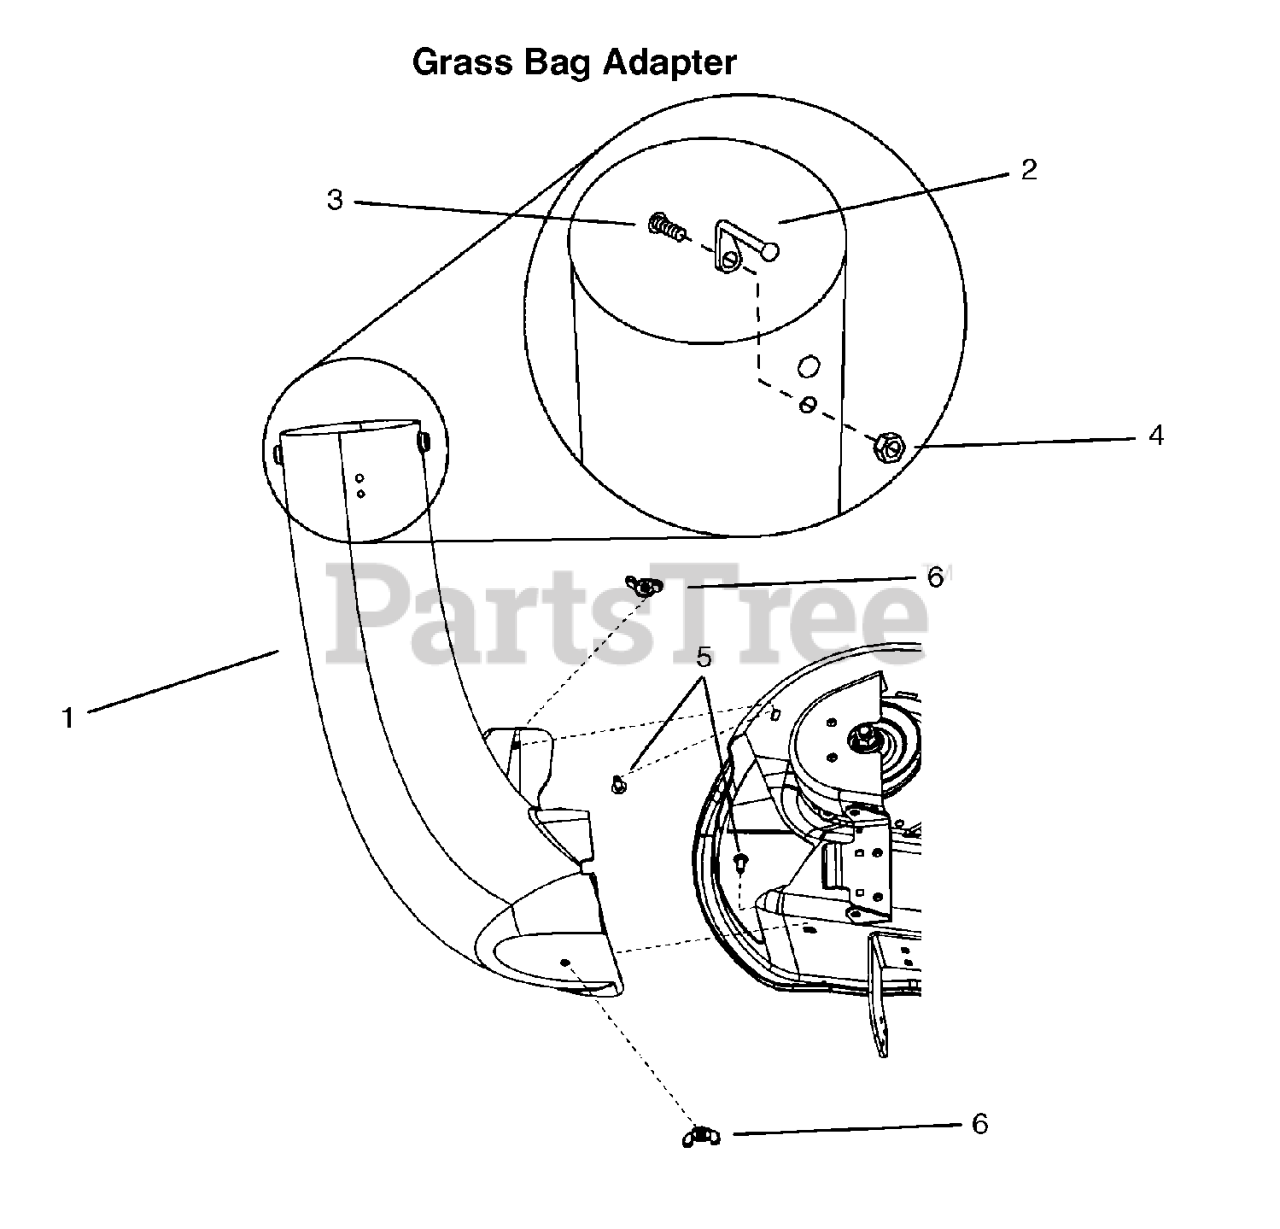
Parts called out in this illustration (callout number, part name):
1	BOOT, 42" BAGGER
1	BOOT, 46" BAGGER
1	BOOT, 52" BAGGER
2	PIN, LATCH
3	BOLT, CARRIAGE, 1/4-20 X 5/8
4	NUT, CENTER LOCK FLANGE 1/4-20
5	BOLT, CARRIAGE, SN, 5/16-18 X 1 1/4 BLK
6	NUT, 5/16-18 WINGNUT
